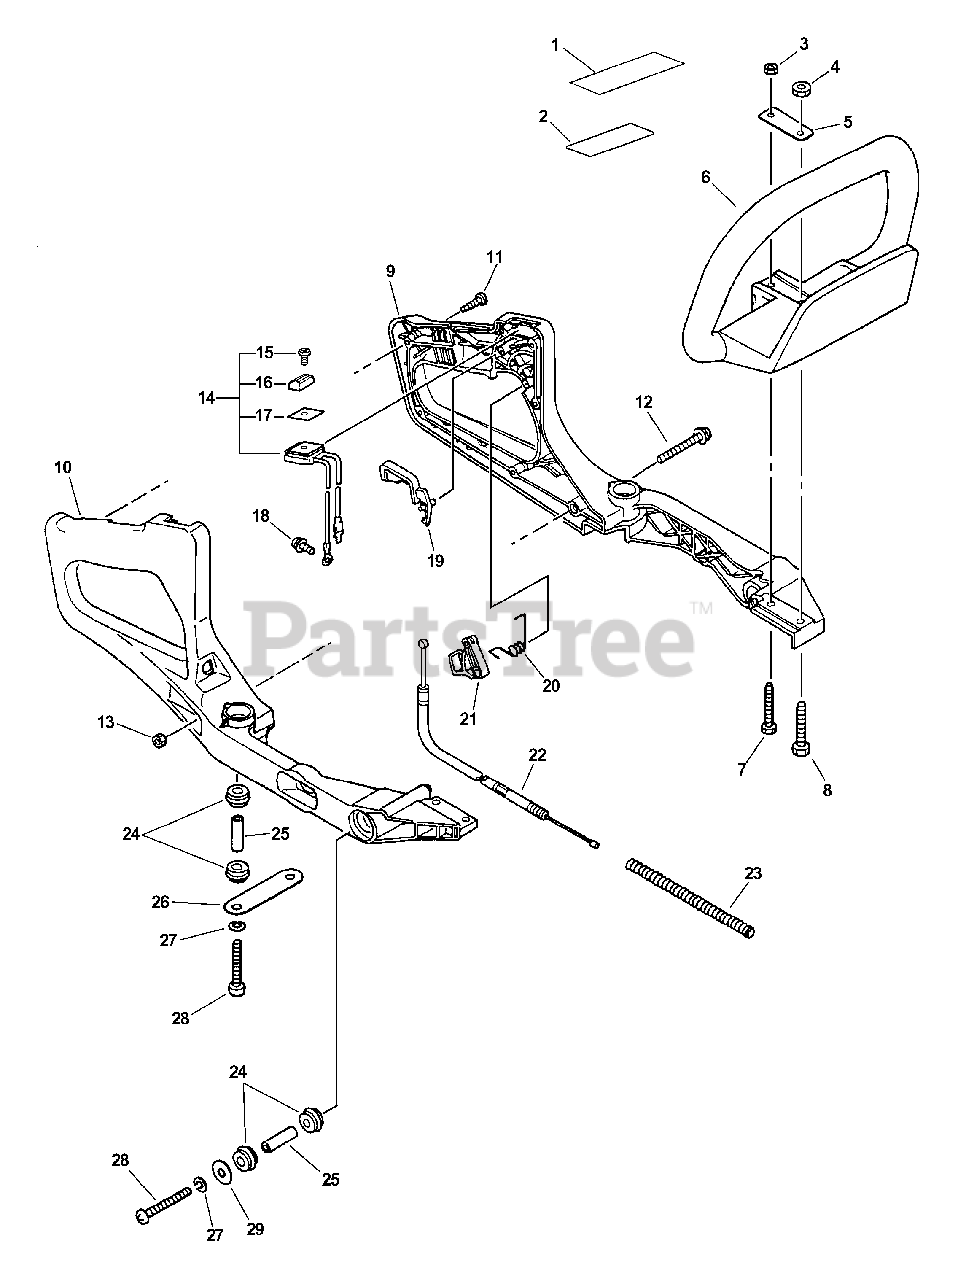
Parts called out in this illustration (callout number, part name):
1	LABEL, CAUTION
2	LABEL, CAUTION
3	NUT M5
4	NUT, HEX M6
5	PLATE, EYE
6	HANDLE, SUPPORT
7	BOLT 5×35 SP
8	BOLT - 6×32
9	HANDLE, REAR - LEFT
10	HANDLE, REAR - RIGHT
11	SCREW 4×25
12	SCREW 5×64
13	NUT M5
14	IGNITION SWITCH ASSY
15	SCREW 3×10
16	KNOB, SWITCH - ORANGE
17	LABEL, SWITCH
18	SCREW 5×10
19	LOCKOUT, THROTTLE
20	SPRING, TORSION
21	TRIGGER, THROTTLE
22	CABLE, THROTTLE
25	SPACER
26	PLATE, EYE
27	WASHER, SPRING 5
28	SCREW 5×40
